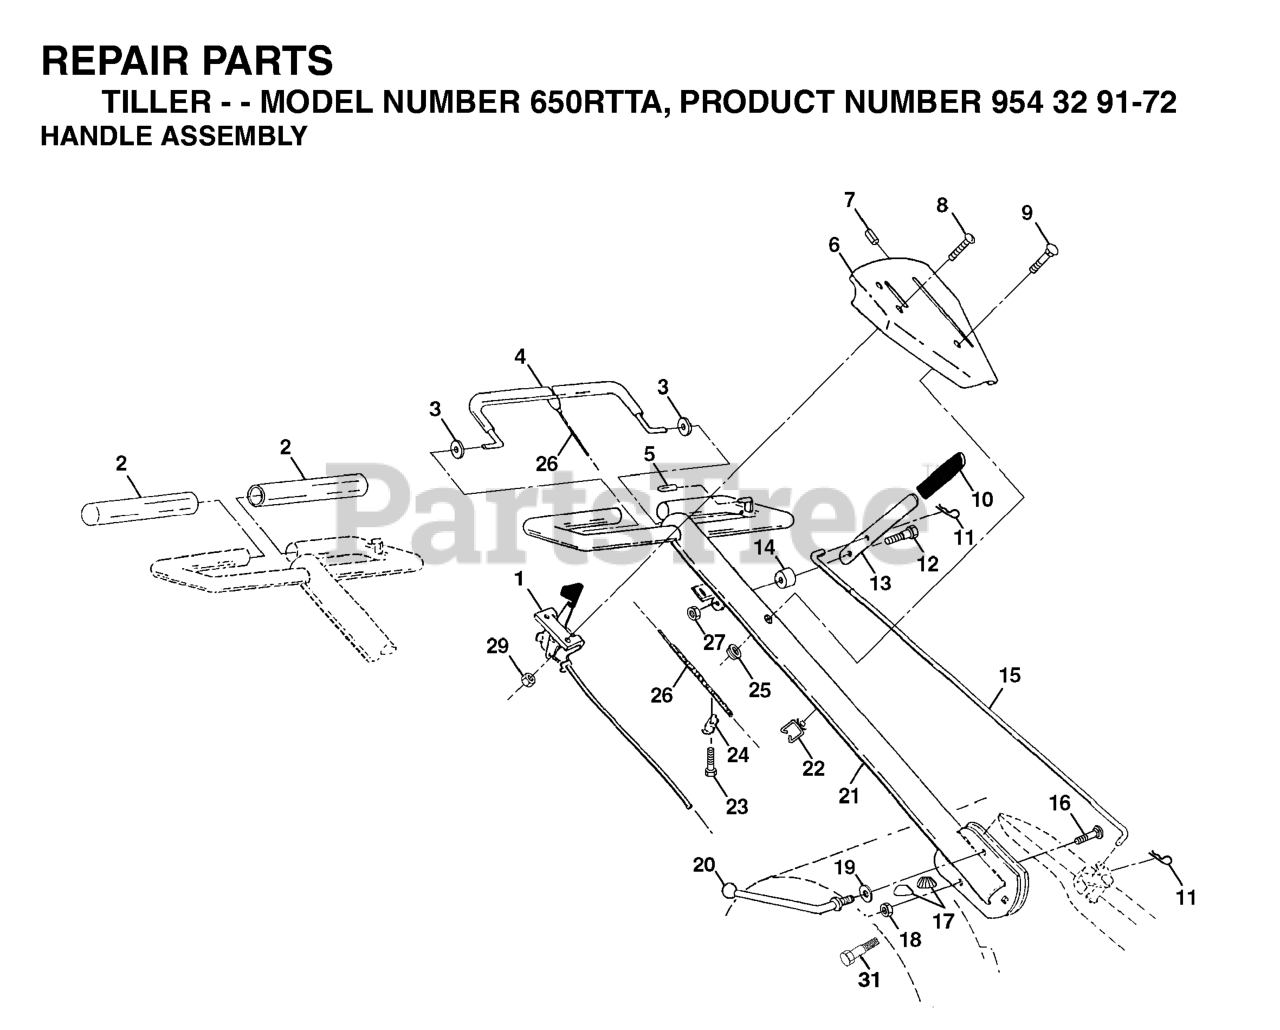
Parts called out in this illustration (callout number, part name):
1	THROTTLE.CONTROL.CRT.TILLER
2	GRIP.HANDLE.TILLER
3	GROMMET HANDLE
4	BAR ASSEMBLY, CONTROL
6	PANEL, CONTROL
7	BUSHING SPLIT
8	SCREW.PNHD.10-24
9	BOLT.5/16-18X2.5
10	GRIP, HANDLE
11	RETAINER M
12	SHOULDER BOLT ST
13	HANDLE, SHIFT
14	GROMMET.RUBBER.CRT.TILLER
15	ROD, SHIFT
16	BOLT D
17	LOCK.HANDLE.CRT
19	WASHER CRT
20	LEVER.LOCK.CRT
21	HANDLE
22	CLIP CABLE
23	TAPPING SCREW
24	CONDUIT.CLIP.PLATED
25	NUT.CENTERLOCK.5/16-
26	CABLE, CLUTCH
27	NUT T
29	NUT **
31	BOLT.PIVOT
